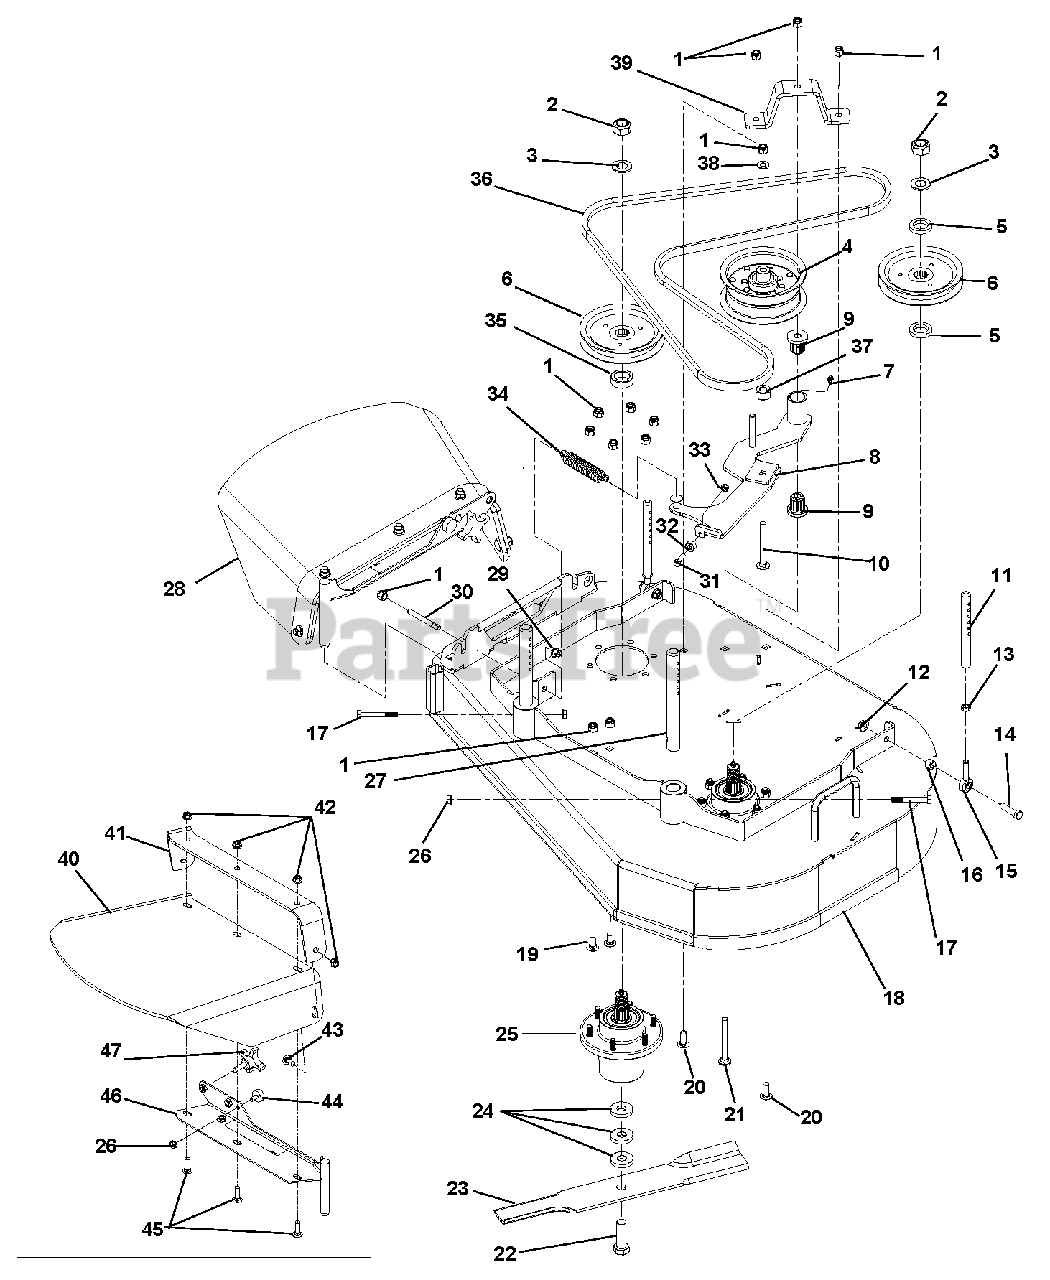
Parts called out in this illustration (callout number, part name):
1	LOCKNUT, 3/8-16 NYLOC Y
2	LOCKNUT, 3/4-16 CROWN C
3	WASHER, .75 X 1.3125 X .113
4	PULLEY, FLAT 5.00 X 2.36 X .375
5	WSHR, FL-STL 1.0 X 1.5 X .25
6	PULLEY, SPLINE SPINDLE SHFLWLK
7	FTG, 1/4-28 STRGT GREASE ZERK
8	WLDT, IDLER ARM 36
9	BRG, FLG M10 X M25 X M27 FLUTED
10	BOLT, 3/8-16 X 3.50 CRG 5 Y
11	ROD, REAR HOC
12	NUT, LK TOP FLG .375-16 YWZC REV
13	NUT, JAM .375-24 YWZC REV
14	BOLT, HEX .38-16 X 1.50 GR5
15	ROD, END 3/8 RH REV
16	BSHG - SLV REV
17	BOLT, 5/16-18 X 2.50 HEX 8 Y
18	ASSY, 36" FLWLK DECK W/DECALS
19	BOLT, RDHDSHSQNK .38-16 X .75 G5
20	BOLT, 3/8-16 X 1.00 CRG 5 SN Y
21	BOLT, 3/8-16 X 3.50 CRG 5
22	BOLT, 5/8-11 X 2.00 HEX 8 Y
23	BLADE, 18"
24	Washer, Blade
25	ASSY, SPINDLE HOUSING
26	LOCKNUT, 5/16-18 WHIZ Y
27	ROD, FRONT HOC
28	ASSY, DISCHARGE SHIELD
29	LOCKNUT, 3/8-16 WHIZ Y
30	ROD, THREADED ADJUSTMENT
31	BOLT, HEX .25-20 X 1.00 GR5
32	BRG, BAL .250 X .688 X .313
33	LOCKNUT, 1/4-20 NYLOC Y
34	SPRING, EXT .875 X .125 X 4.25 Y
35	SPACER, 1.500 X 1.000 X .510 Y
36	BELT, HB 85.1 EL AMD
37	SPACER, .437 X 1.00 X .58 SMLS
38	WASHER, .406 X .813 X .065 FLAT Y
39	STRAP, IDLER 36
40	SHIELD, WALK RUBBER DISCHARGE
41	STRAP, GRAVELY WLK RUBBER DIS
42	NUT, SPNLK-FLG .375-16
43	BOLT, RDHDSQNK .38-16 X 1.00 G5
44	BUMPER, RUBBER
45	BOLT, RDHDSQNK .38-16 X 1.25 G5
46	WLDT. DISCHARGE
47	KNOB, 3/8 X 1.25 - 4 PRONG
